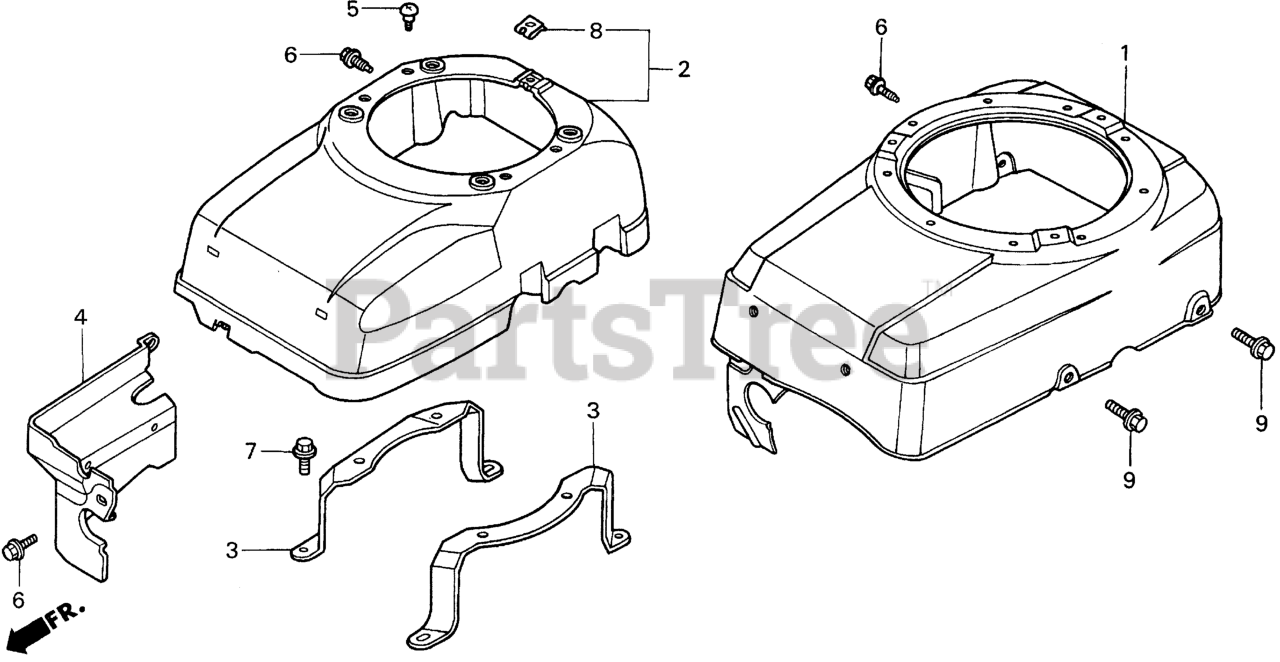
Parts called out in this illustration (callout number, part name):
2	COVER, FAN *NH1* (BLACK)
3	BRACKET, FAN COVER
5	SCREW, SPECIAL (6X8)
6	BOLT, FLANGE (6X12) (CT200)
7	BOLT, FLANGE (6X16)
8	NUT, SPRING (6MM)
